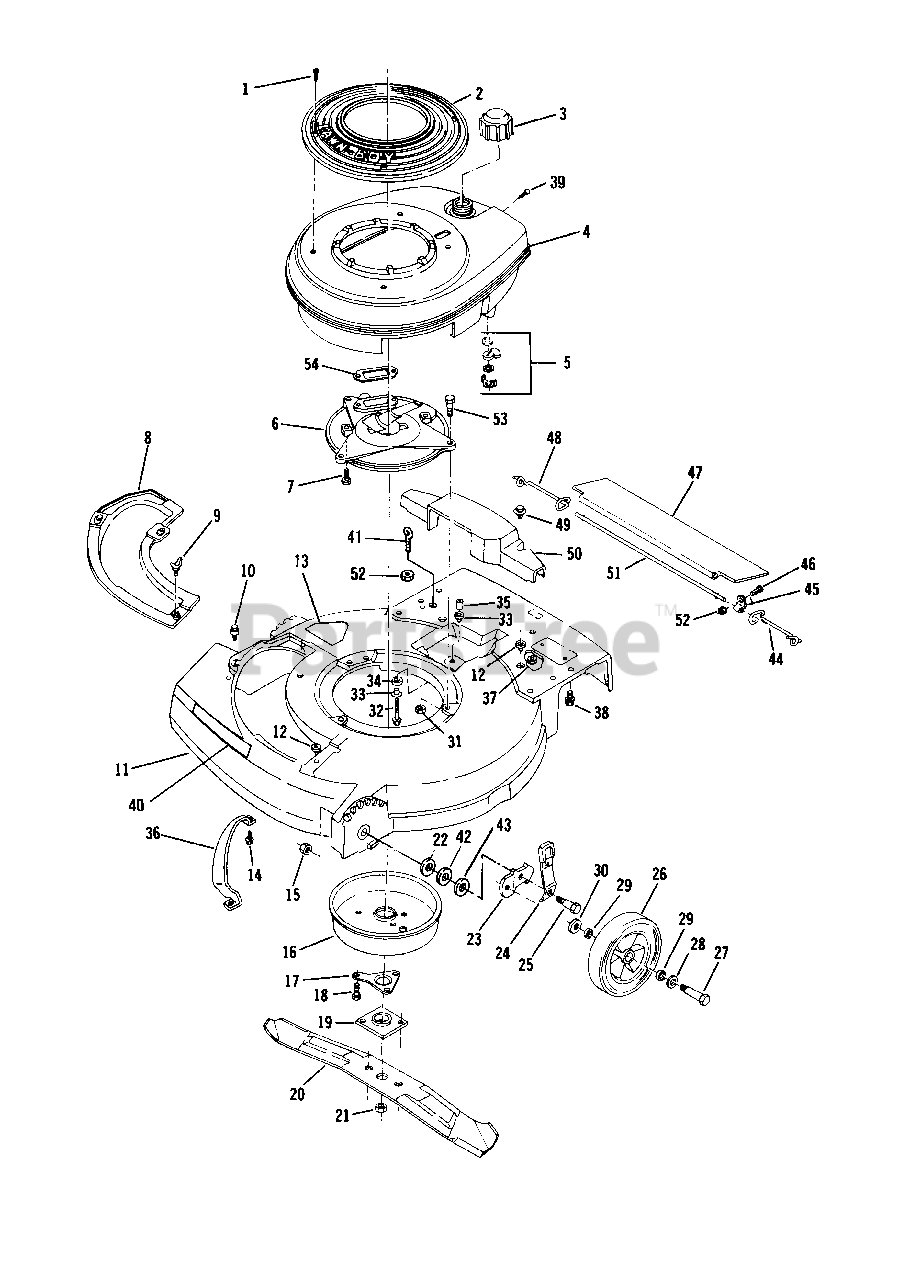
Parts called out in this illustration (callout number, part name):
1	Screw
2	Cover-Shroud
3	Fuel Cap
4	Shroud-Engine
5	Fuel Shut-Off Assembly
6	Plate Muffler
7	Screw-Muffler Plate to Block
8	Cover Plate
9	Wing Screw
10	Screw-Plate and Chute Mounting
11	Housing
12	Grommet
13	Decal-Blade Contact Warning
14	Screw
15	Nut
16	Muffler Cover Assembly
17	Support-Crankshaft
18	Screw-Muffler to Muffler Plate
19	Collar and Plate Assembly
20	Blade-21"
21	Nut-Blade
22	Washer
23	Bracket-Wheel Height Adjust
24	Knob and Spring Assembly
25	Bolt-Shoulder
26	Wheel-Front
27	Bolt-Wheel-Front
28	Washer
29	Washer-Felt
30	Washer
31	Nut-Muffler Plate to Housing
32	Screw
33	Spacer
34	Grommet
35	Spacer
36	Toe Bar
37	Nut-Ball Stud
38	Screw-Handle Bracket
39	Screw-Shroud to C.D. Bracket
40	Decal-Headliner
41	Eyebolt-Starter Rope
42	Washer-Shim-Wheel Height Adjust Bracket
43	Washer-Shim-Wheel Height Adjust Bracket
44	Spring-L.H.
45	Clamp
46	Screw
47	Shield-Trailing
48	Spring-R.H.
49	Screw-Axle Cover Mounting
50	Cover-Drive Axle
51	Rod-Trailing Shield
52	Nut-Trailing Shield and Eyebolt
53	Screw-Muffler Plate to Housing
54	Gasket-Exhaust
